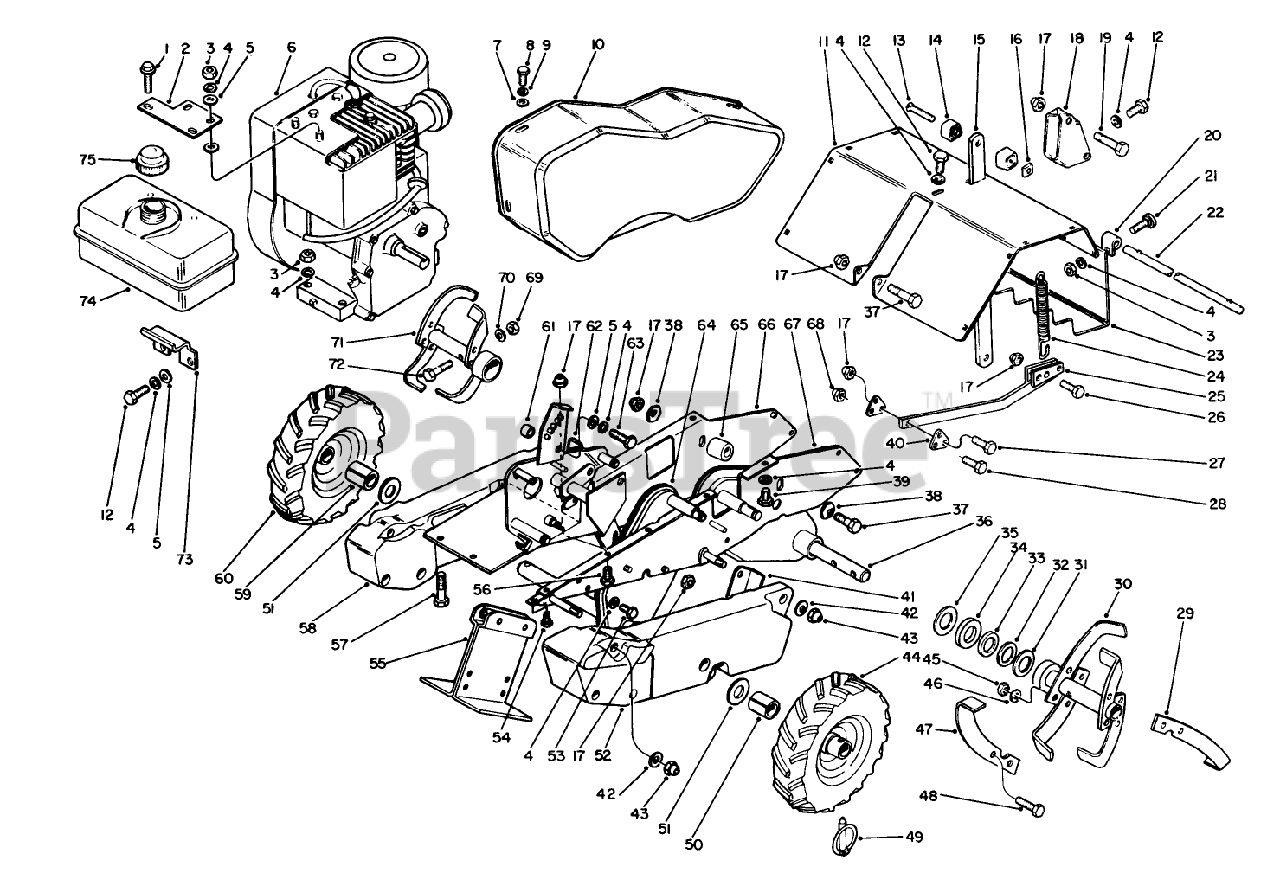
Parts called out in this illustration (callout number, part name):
2	Top Mounting-Gas Tank
3	NUT-HEX
4	WASHER-LOCK
5	WASHER-PLAIN
6	Engine (Incl. Ref. #1, 2, 8 73-75)
7	WASHER-FLAT
8	SCREW-HH
9	WASHER-LOCK
12	SCREW-HH
16	Nut-Square
17	NUT-LOCK, CONE
19	SCREW-HH
21	BOLT-CARR
26	SCREW-HH
27	SCREW-HH
28	SCREW-HH
39	SCREW-HH
42	WASHER-FLAT
43	NUT-LOCK, CONE
45	NUT-HEX
46	WASHER-LOCK
53	SCREW-HH
57	SCREW-HH
63	SCREW-HH
65	Spacer
68	NUT-LOCK, CONE
69	NUT-HEX
70	WASHER-LOCK
73	Bottom Mounting-Gas Tank
74	Gas Tank
75	Gas Cap
